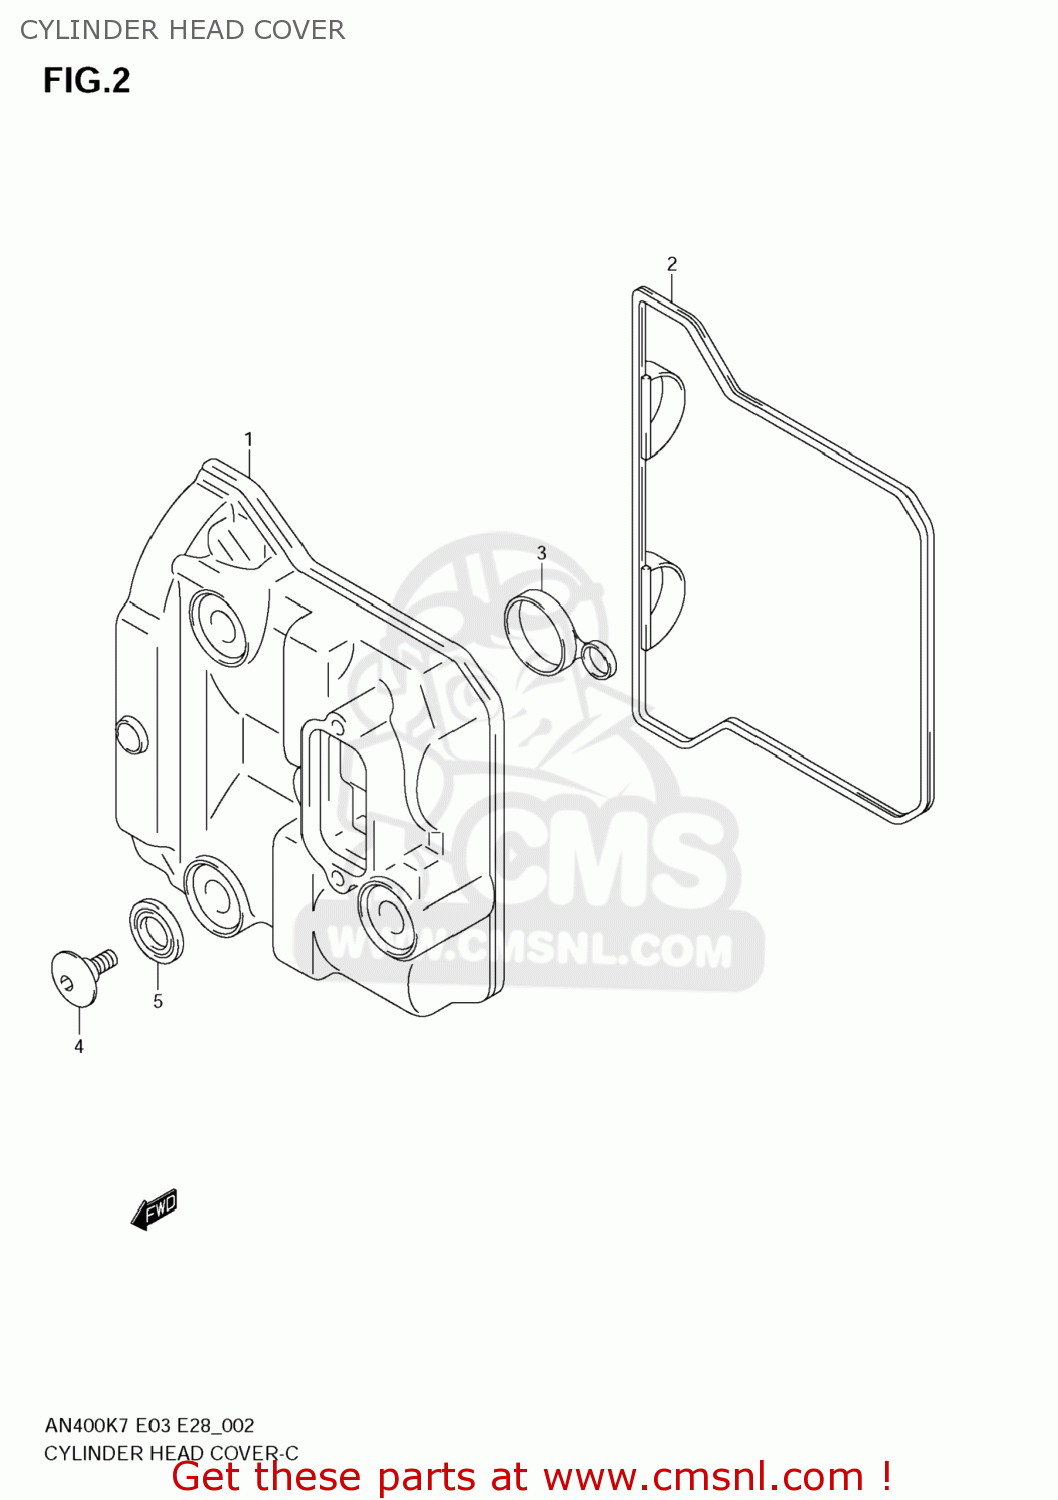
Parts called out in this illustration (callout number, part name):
1	COVER,CYLINDER HEAD
2	GASKET,CYL HEAD COVER NO.1 (NAS)
3	GASKET,CYL HEAD COVER NO.2 (NAS)
4	BOLT(7X17.5)
5	WASHER,CYL HEAD COVER
